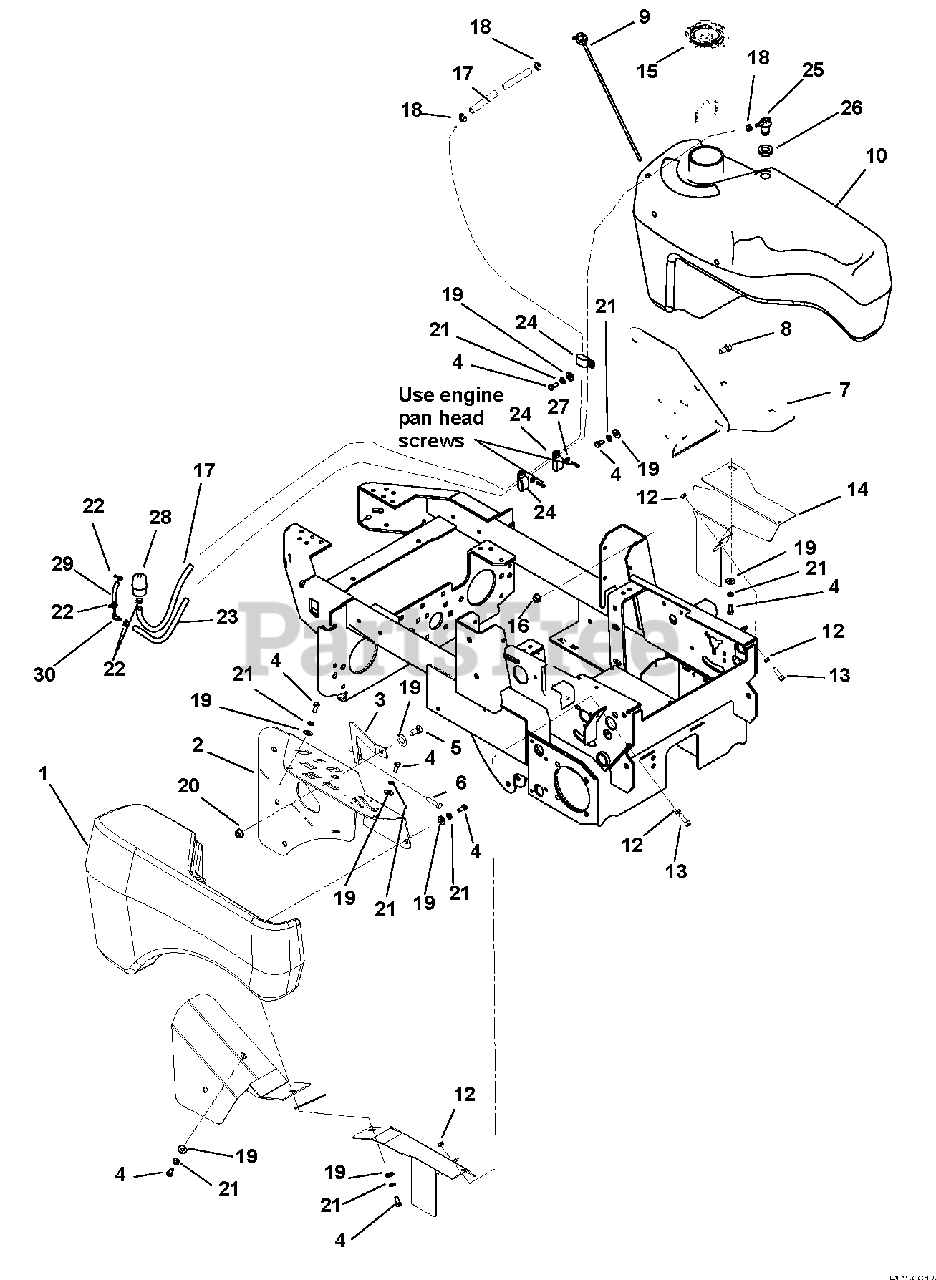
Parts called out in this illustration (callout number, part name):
1	Fender, Right Hand
2	Weldment, Control Panel
3	Stiffener, Fender
4	Bolt, Hex .31-18 x .75
5	Bolt, Hex .38-16 x .75 Grade 5
6	Screw, Tapping .38-16 x .50 Hex Washer Head Thread Rolling
7	Weldment, Fuel Tank Bracket (Outfront)
8	Bolt, Hex .50-13 x 1.00 Grade 5
9	Assembly, Fuel Line with 90° Fitting
10	Tank, Fuel Left Hand Rapid XZ
11	Cover, Tire Right Hand
12	Nut, Hex Jam .375-16
13	Bolt, Hex .38-16 x 1.25 Grade 5
14	Cover, Tire Left Hand
15	Cap, Fuel
16	Nut, .50-13 Nyloc Flange
17	Gas Line, Bulk 1/4" I.D.
18	Clamp, Hose Wire .490/.510 x .116
19	Washer, Flat Steel .38 x .875 x .083
20	Nut, Flange .375-16
21	Washer, Lock .31 x .078 Regular YWZC
22	Clamp, Hose Spring .188
23	Hose, .25 Low-PERM Bulk Gas
24	Clamp, Insulated Tube 5/8 YWZC
25	Valve, Combination
26	Grommet, Remote Vent Nitrile
27	Washer, Flat-Steel .25 x .562 .049 YWZC
28	Fuel Filter, Engine
29	Hose, Low-Perm Bulk Gas .188
30	Fitting, 90° Vacuum 3/16 x 1/4
